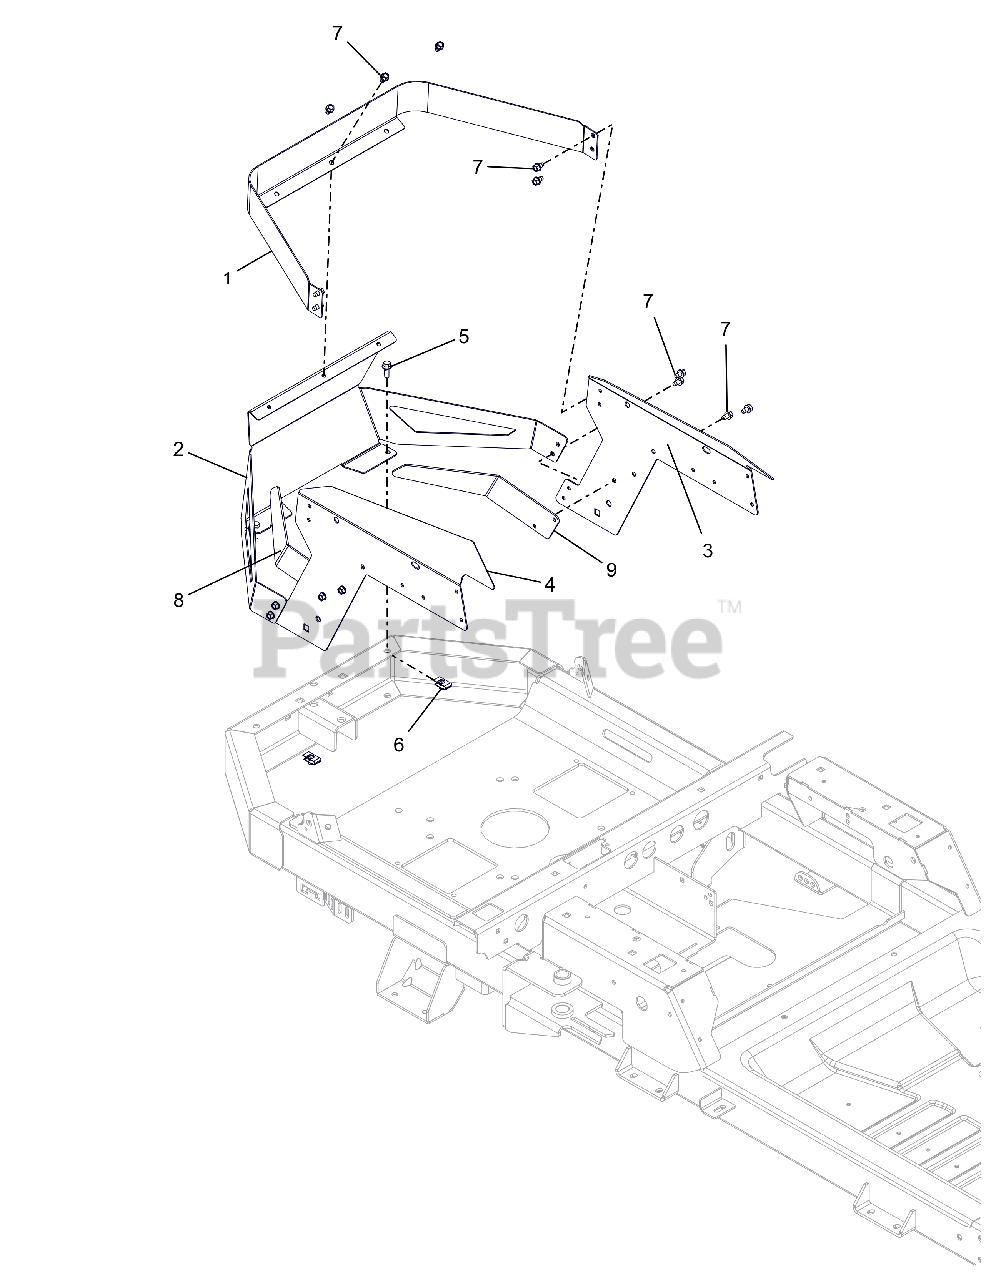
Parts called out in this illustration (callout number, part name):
1	GUARD, ENGINE -TOP TRIM
2	GUARD, ENGINE-BOTTOM BLACK
3	PANEL, LEFT REAR RENDER MOUNT
4	PANEL, RIGHT REAR FENDER MOUNT
5	BLT,HEX-FLG .25-20X.75 G5 BFP
6	NUT-RTNR .25-20X.56
7	SCR,TAP .25-20X.375 HWH TR ZCC
8	SHIELD, RH, ENGINE GUARD VALVE
9	SHIELD, LH, ENGINE GUARD VALVE
